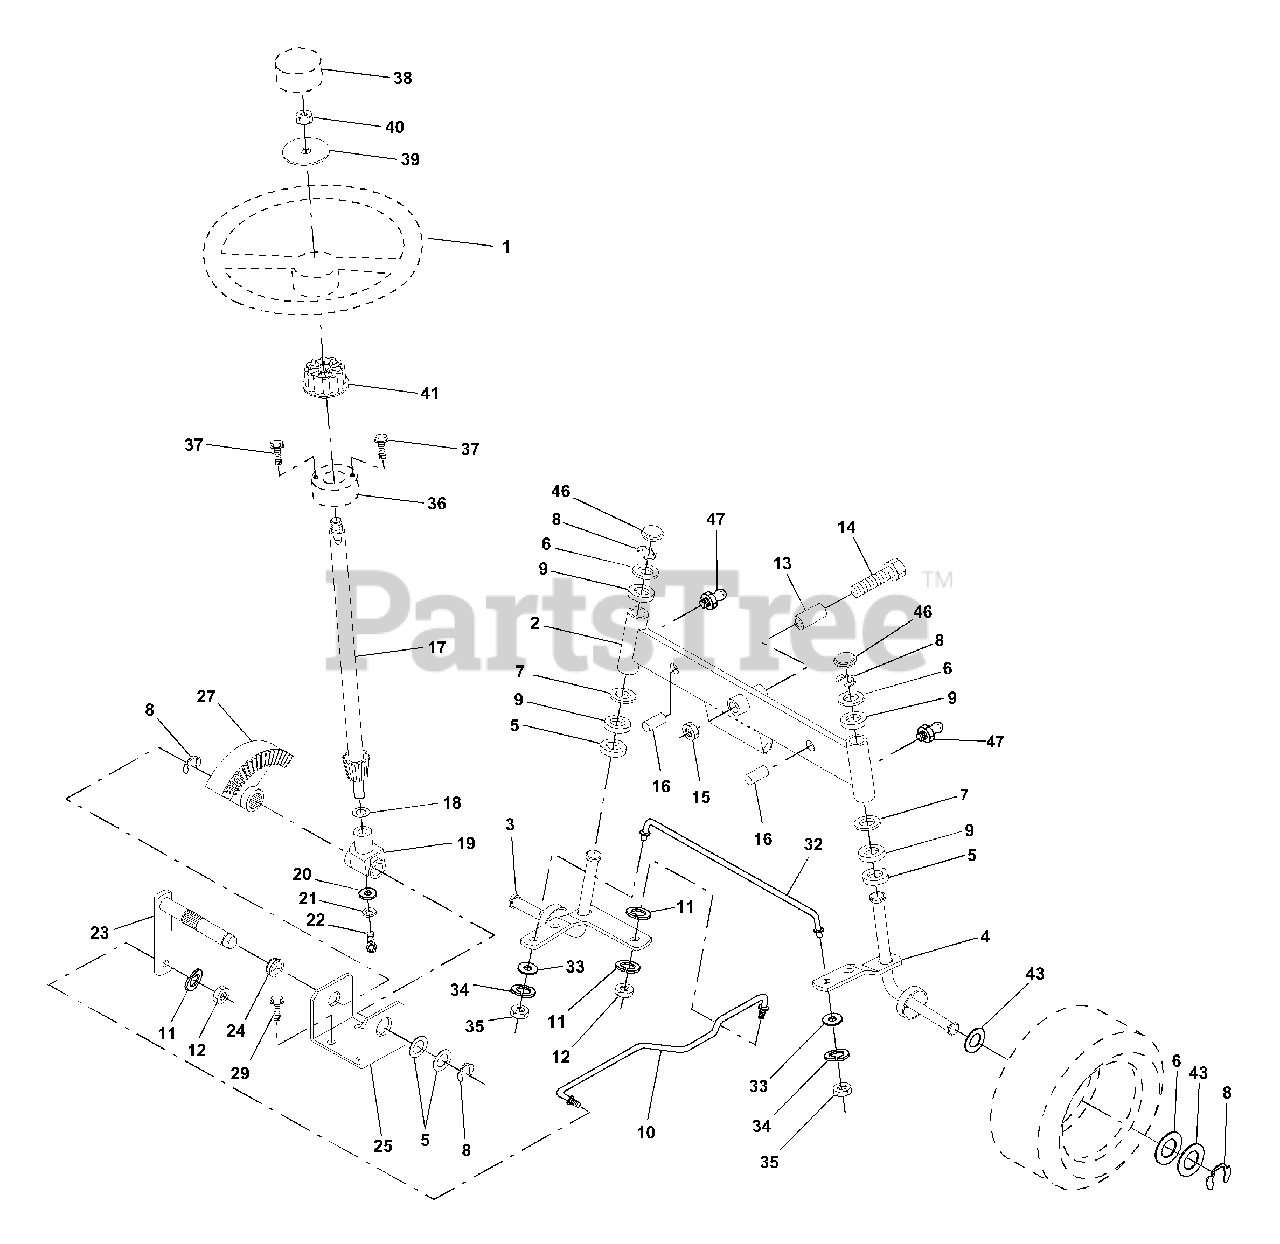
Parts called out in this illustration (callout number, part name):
1	Wheel Steering
2	Axle Asm Fr LT W/gzks 38/42
3	Spindle Asm LH
4	Spingle Asm RH
5	Bearing Race Thrust Harden
6	Washer 25/32 X 1-5/8 X 16 Ga
7	Washer 27/32 X 1-1/4 X 16 Ga
8	Ring Klip #t5304-75
9	Bearing Col Strg
10	Link Drag Sol Ball Jt
11	Washer Lock Hvy Hlcl Spr 3/8
12	Nut Fin 3/8-24 Unf
13	Spacer Bearing Axle Front
14	Bolt Hex 5/8-11 Unc X 3-1/2
15	Nut Lock Flange 5/8-11 Unc
16	Pin Axle 5/8 X 1 55/1 54 Lg
17	Shaft Asm Strg 18 31x3/4
18	Washer Thrust 515x 750x 033
19	Suport Shaft
20	Washer Shim 1/4 X 5/8 X 062
21	Washer Lock Hvy Helical 1/4
22	Screw Hex Socket 1/4-20 X 5/8
23	Shaft Asm Pittman
24	Nyliner Snap In
25	Bracket Steering
27	Gear Sector
29	Screw Thdrol 3/8-16x3/4 Ty-tt
32	Rod Tie Wire Form
33	Washer 11/32 x 12/16 x 16 Ga.
34	Washer, Lock, Hvy Hlcl Spr 5/16
35	Locknut 5/16-24 Unf
36	Bushing Link Drag
37	Screw Slftp #10-16 X 1/2 Ty-b
38	Insert Cap Strg Wh Aut
39	Washer 53 X 2 25 X 160
40	Nut Hex Jam Taplock 1/2-20 Unf
41	Adapter Wheel Strg
43	Washer 25/32 X 1 1/4 X 16 Ja
46	Cap Spindle Fr Top
47	Fitting Grease
